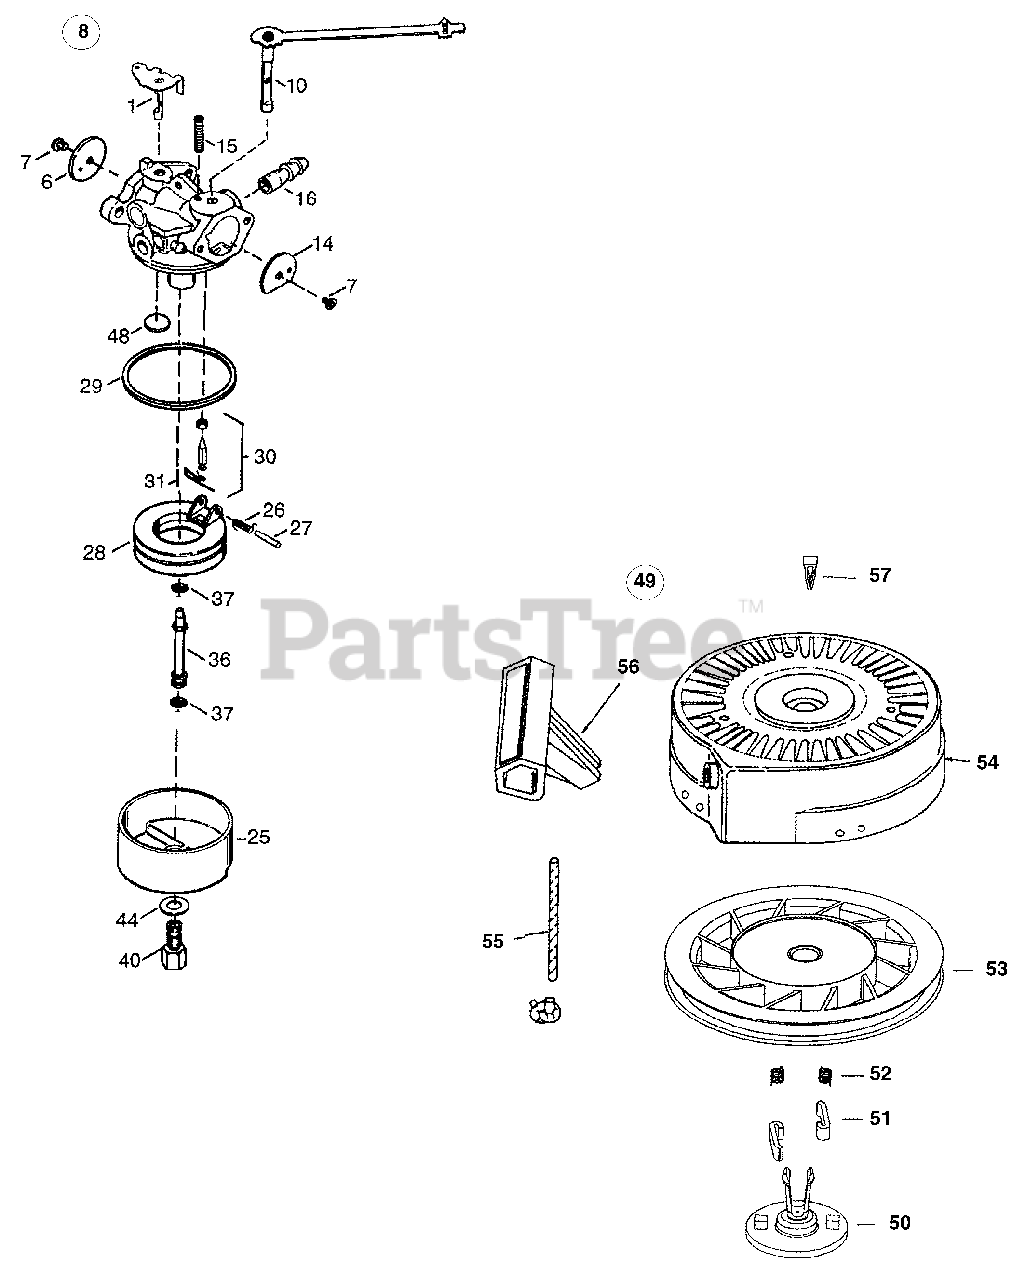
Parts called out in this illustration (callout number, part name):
1	Throttle Shaft & Lever Ass'y
6	Throttle Shutter
7	Shutter Screw
8	Carburetor Assembly
10	Choke Shaft & Lever Ass'y
14	Choke Shutter
15	Choke Positioning Spring
16	Fuel Fitting
25	Float Bowl
26	Float Dampening Screw
27	Float Shaft
28	Float
29	Float Bowl O-Ring
30	Inlet Needle, Seat & Clip
31	Spring Clip
36	Main Nozzle Tube
37	O-Ring Main Nozzle Tube
40	High Speed Bowl Nut
44	Bowl Nut Washer
48	Welch Plug, Atmospheric Vent
49	Rewind Starter Ass'y
51	Starter Dog
52	Dog Spring
53	Pulley Ass'y
54	Starter Housing Ass'y
55	Starter Rope (98")
56	Starter Handle
57	Locking Tab
